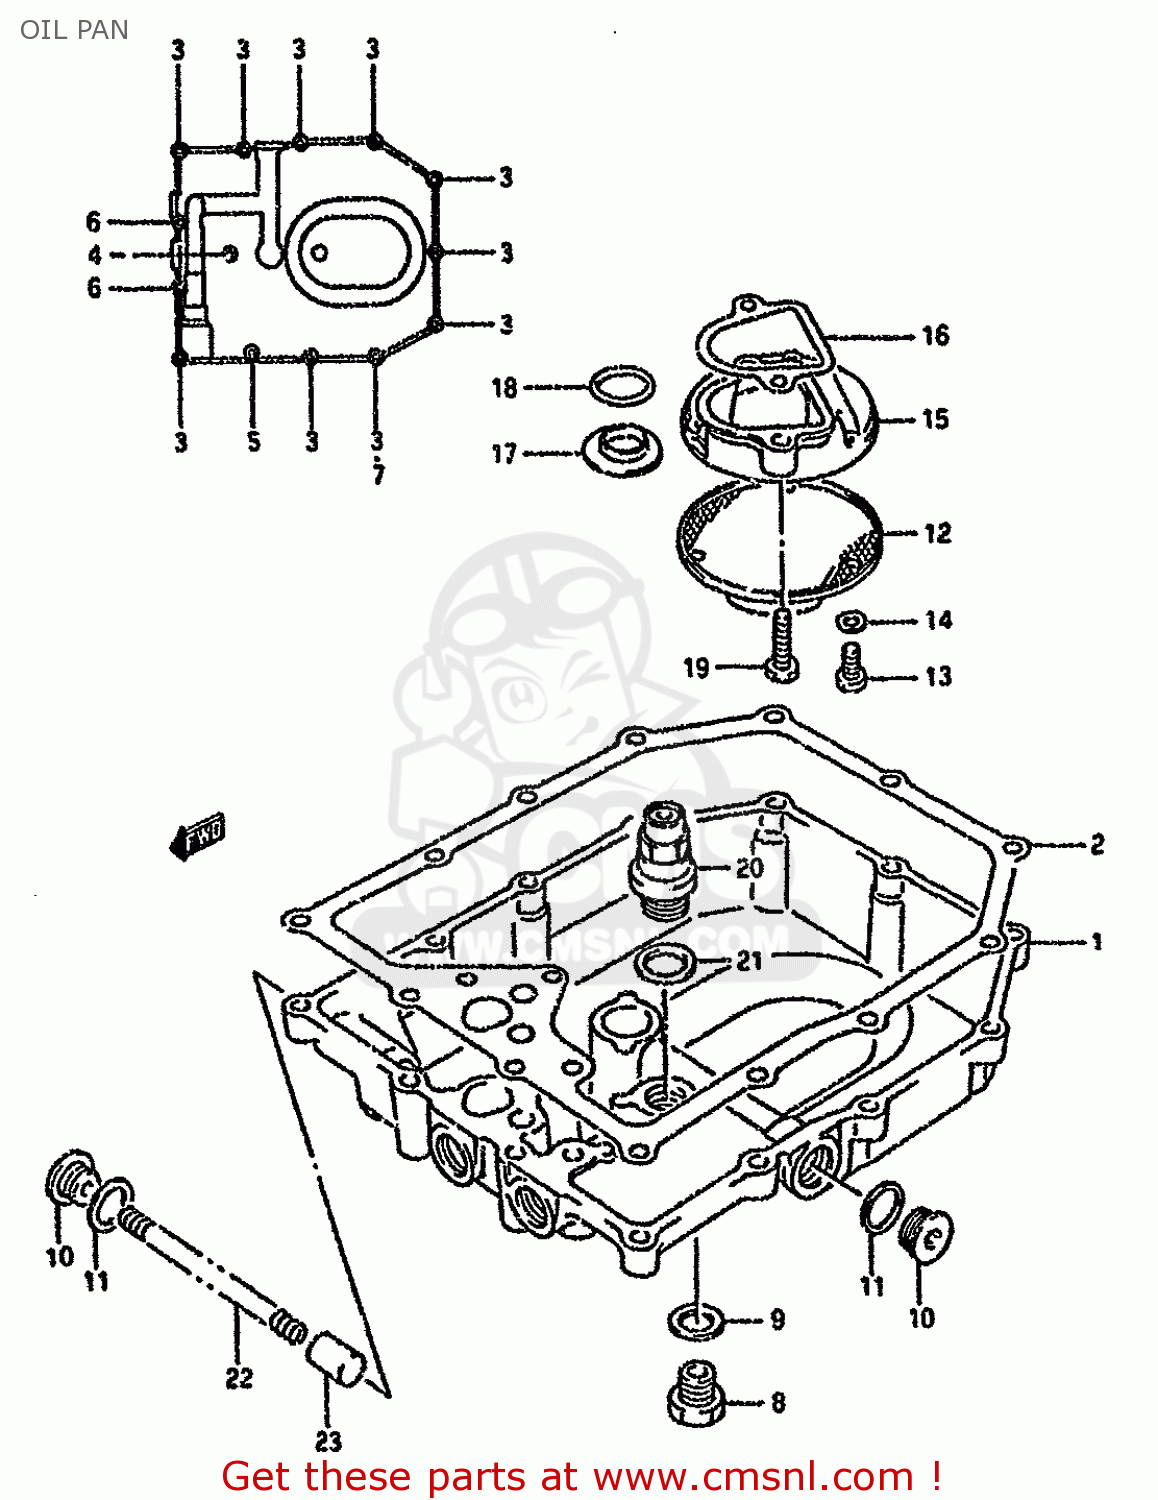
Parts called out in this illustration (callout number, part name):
1	PAN,OIL
2	GASKET,OIL PAN (NAS)
3	BOLT
4	BOLT
5	BOLT
6	BOLT
7	GASKET(5.8X11X1.2) (NAS)
8	PLUG
9	GASKET(13.8X18.8X4.8) (NAS)
10	PLUG
11	GASKET(16X22X2) (NAS)
12	STRAINER,ENGINE OIL
13	BOLT
14	WASHER,LOCK
15	PROTECTOR,OIL STRAINER
16	O-RING
17	GASKET,OIL OUTLET (NAS)
18	O RING(D:3.2,ID:17.8)
19	BOLT
20	VALVE ASSY,OIL RELIEF
21	GASKET(16X22X2) (NAS)
22	SPRING
23	PLUNGER,OIL CONTROLL
